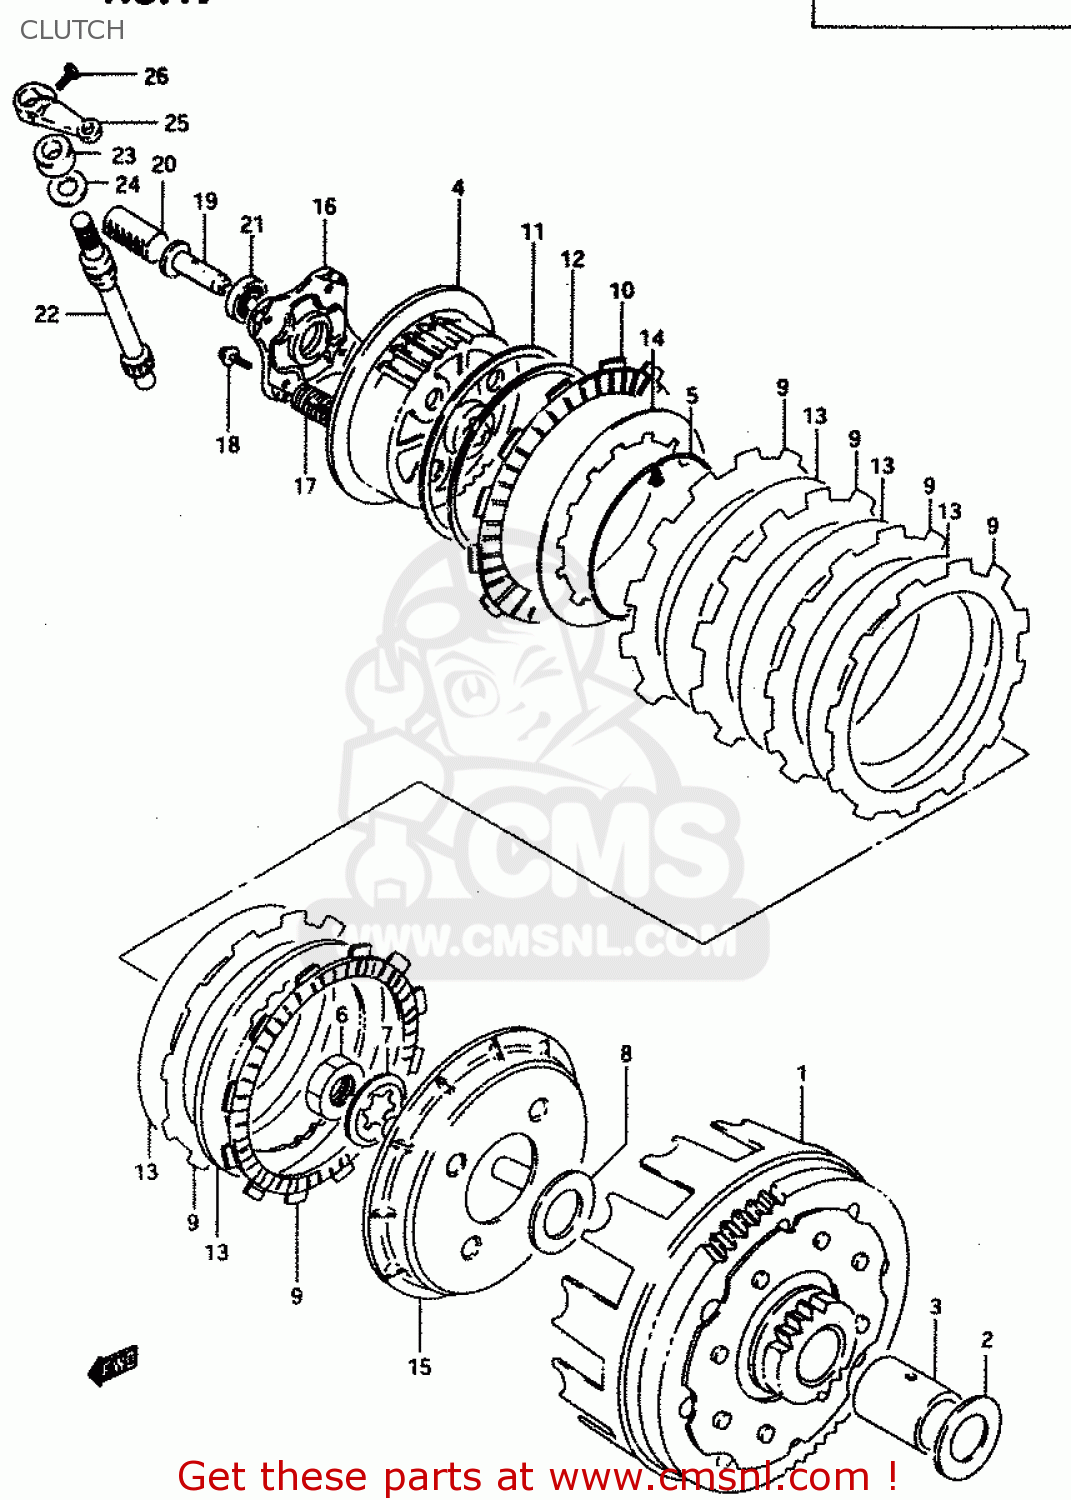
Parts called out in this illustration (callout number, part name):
1	GEAR ASSEMBLY,PRIMARY DRIVE
2	WASHER
3	SPACER(22X28X32.5)
4	HUB,CLUTCH SLEEVE
5	RING,WAVE WASHER STOPPER
6	NUT
7	WASHER,LOCK
8	WASHER
9	PLATE,CLUTCH DRIVE (NAS)
10	PLATE,CLUTCH DRIVE NO (NAS)
11	SEAT,WAVE WASHER
12	WASHER
13	PLATE,CLUTCH DRIVEN(T:1.6) (NAS)
14	PLATE,CLUTCH DRIVEN (NAS)
15	DISC,CLUTCH PRESSURE
16	PLATE,RELEASE
17	SPRING
18	BOLT
19	PIECE,CLUTCH PUSH
20	RACK,CLUTCH RELEASE
21	BEARING(12X28X8)
22	PINION,CLUTCH RELEASE
23	SEAL,OIL (12X22X9)
24	WASHER (14.2X22X1)
25	ARM,CLUTCH RELEASE
26	BOLT
